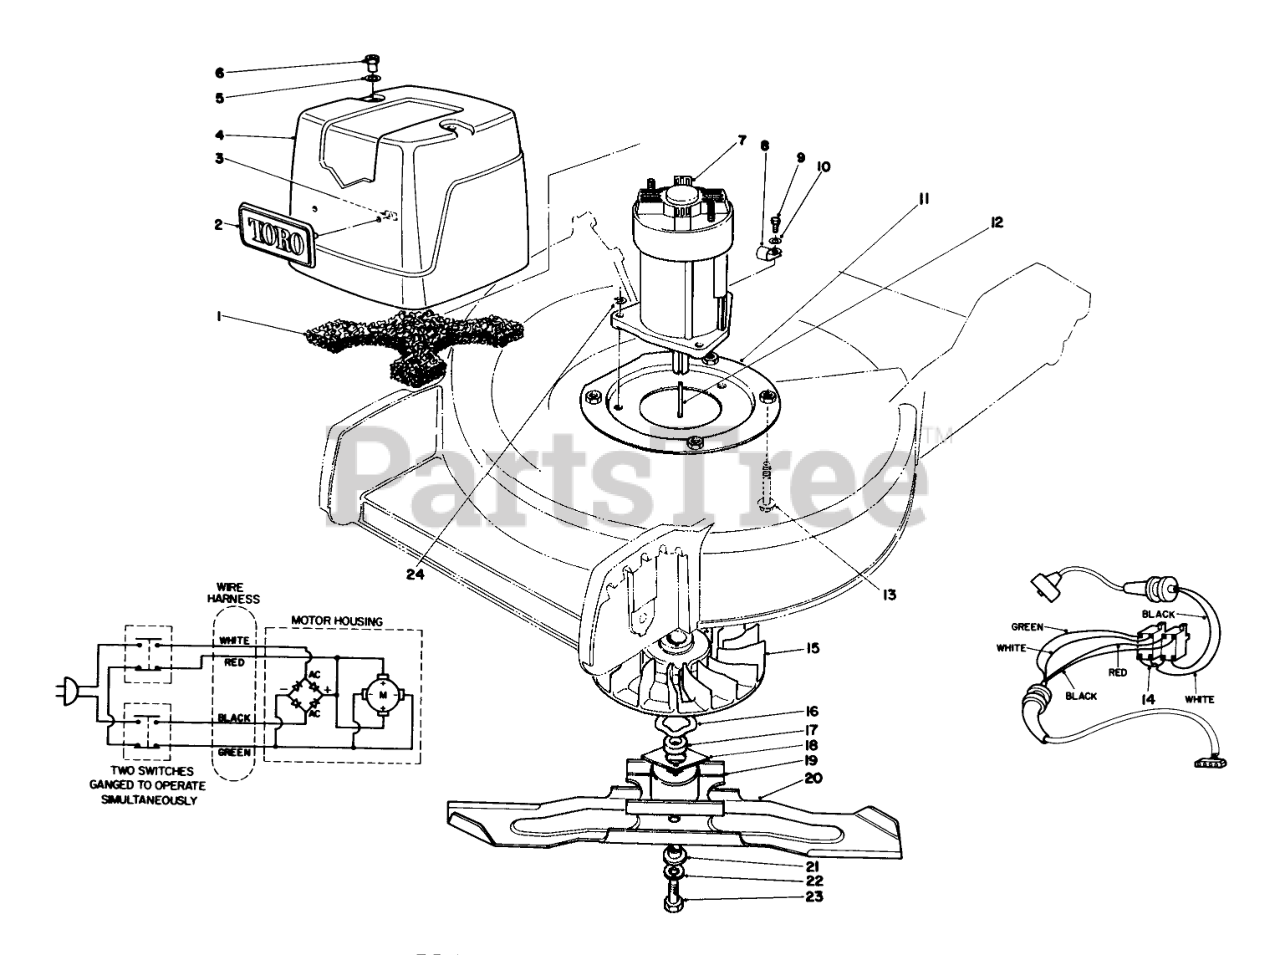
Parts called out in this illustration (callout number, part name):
1	FILTER F/W
2	TORO LOGO PLT
3	Receiver-Stud
4	Shroud-Motor
5	WASHER F/W
6	NUT F/W
7	Motor-Electric
8	CLAMP
9	SCREW-HH
10	WASHER-FLAT
11	MOTOR MOUNT ASM WA
12	KEY-SQUARE
13	SCREW-HHF
14	BRAKE WIRE
15	FAN F/W
16	WAVE WASHER
17	BLADE RETAINER SPACER
18	FAN DRIVER
19	BLADE RETAINER WA
20	Blade
21	BLADE SPACER
22	WASHER-LOCK/SP
23	SCREW-HH
24	WASHER-LOCK/EXT
